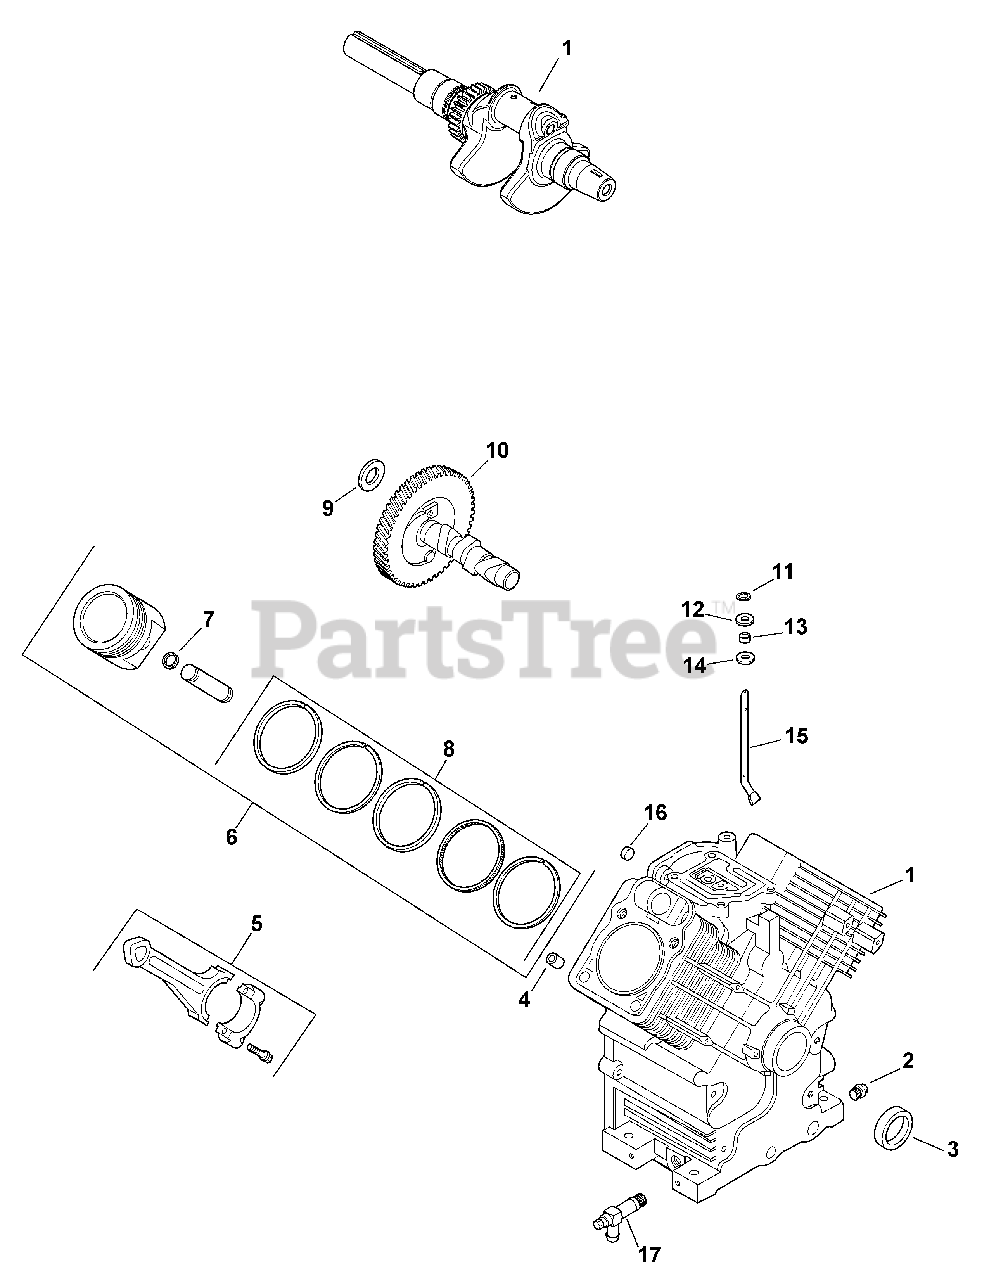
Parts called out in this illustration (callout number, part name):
1	Crankshaft
1	Crankcase
2	Plug, sq. head 3/8"
3	Seal, front oil
4	Pin, locating
5	Connecting Rod (Std.)
5	Connecting Rod (.25)
6	Piston w/Ring Set (Std.)
6	Piston w/Ring Set (.08)
6	Piston w/Ring Set (.25)
6	Piston w/Ring Set (.50)
7	Retainer, piston pin
8	Ring Set (Std. & .08)
8	Ring Set (.25)
8	Ring Set (.50)
9	Shim, camshaft (A.R.) red
9	Shim, camshaft (A.R.) black
9	Shim, camshaft (A.R.) white
9	Shim, camshaft (A.R.) blue
9	Shim, camshaft - yellow
9	Shim, camshaft (A.R.) green
9	Shim, camshaft (A.R.) gray
10	Camshaft
11	Retainer, ring
12	Washer, plain 9 mm
13	Seal, governor cross shaft
14	Washer, plain 1/4"
15	Shaft, governor cross
17	Valve, oil drain
